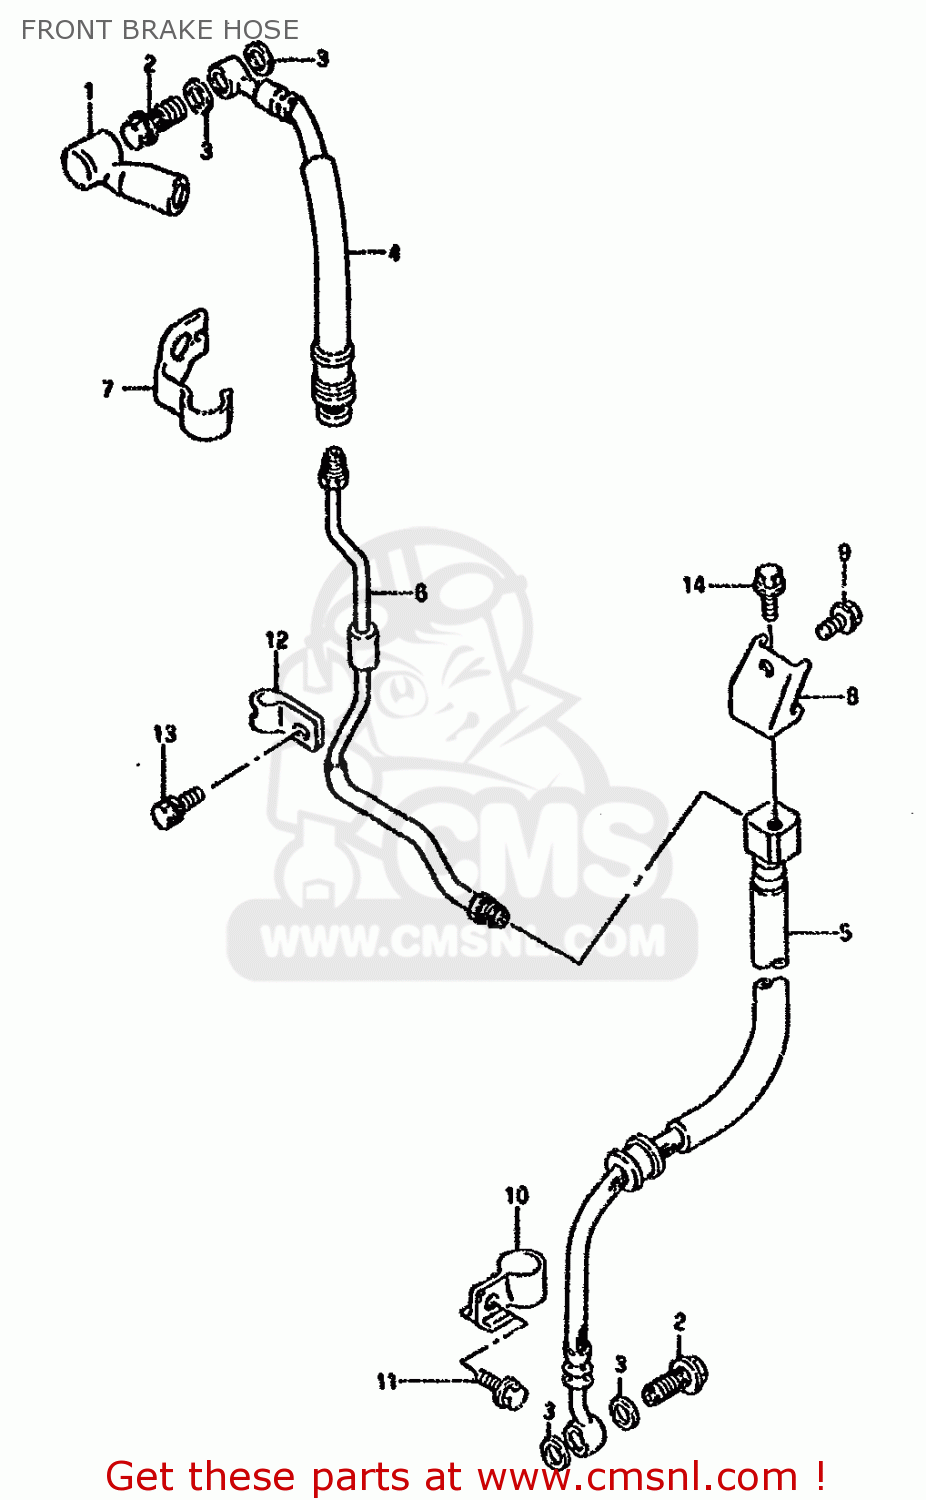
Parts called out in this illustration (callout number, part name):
1	BOOT,MASTER CYLINDER
2	BOLT UNION
3	WASHER(10X15X1.5)
4	HOSE,FR BRAKE NO.1
5	HOSE,FR.BRAKE
6	PIPE,FR BRAKE
7	CLAMP,FR BRAKE HOSE NO.1
8	BRACKET,FR BRAKE HOSE NO.2
9	BOLT
10	CLAMP,FR BRAKE HOSE NO.2
11	BOLT
12	CLAMP
13	BOLT
14	BOLT
